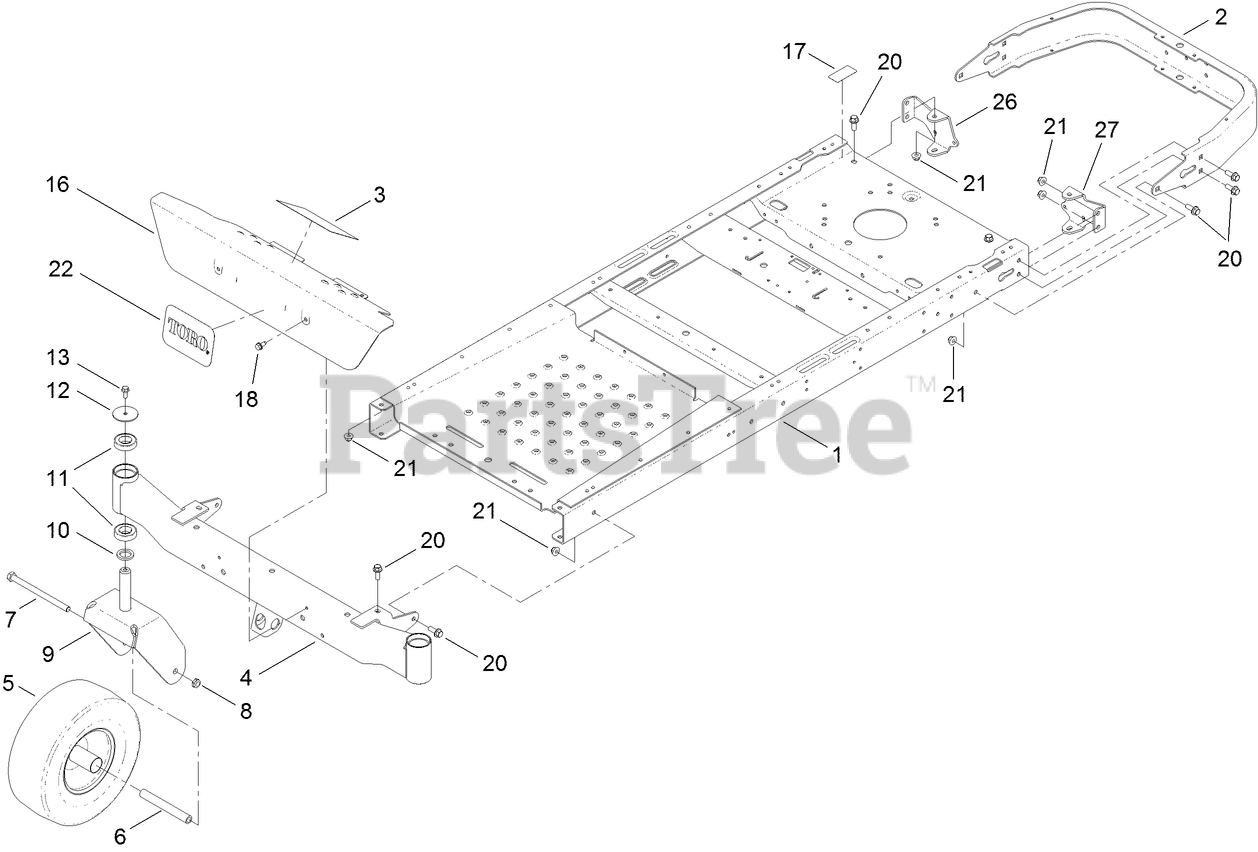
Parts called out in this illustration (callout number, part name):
2	BUMPER-REAR (WIDE)
4	AXLE-FRONT, WIDE
5	13 INCH WHEEL AND TIRE ASM
6	SPANNER
7	SCREW-HH
8	NUT-HEX
9	FORK-CASTER
10	WASHER-THRUST
11	BEARING-BALL
12	WASHER
13	SCREW-HHF
17	DECAL-BYPASS
18	SCREW-HWHTF
20	SCREW-HHF
21	NUT-HF, NI
22	DECAL
26	MOUNT-HYDRO, REAR (RH)
27	MOUNT-HYDRO, REAR (LH)
